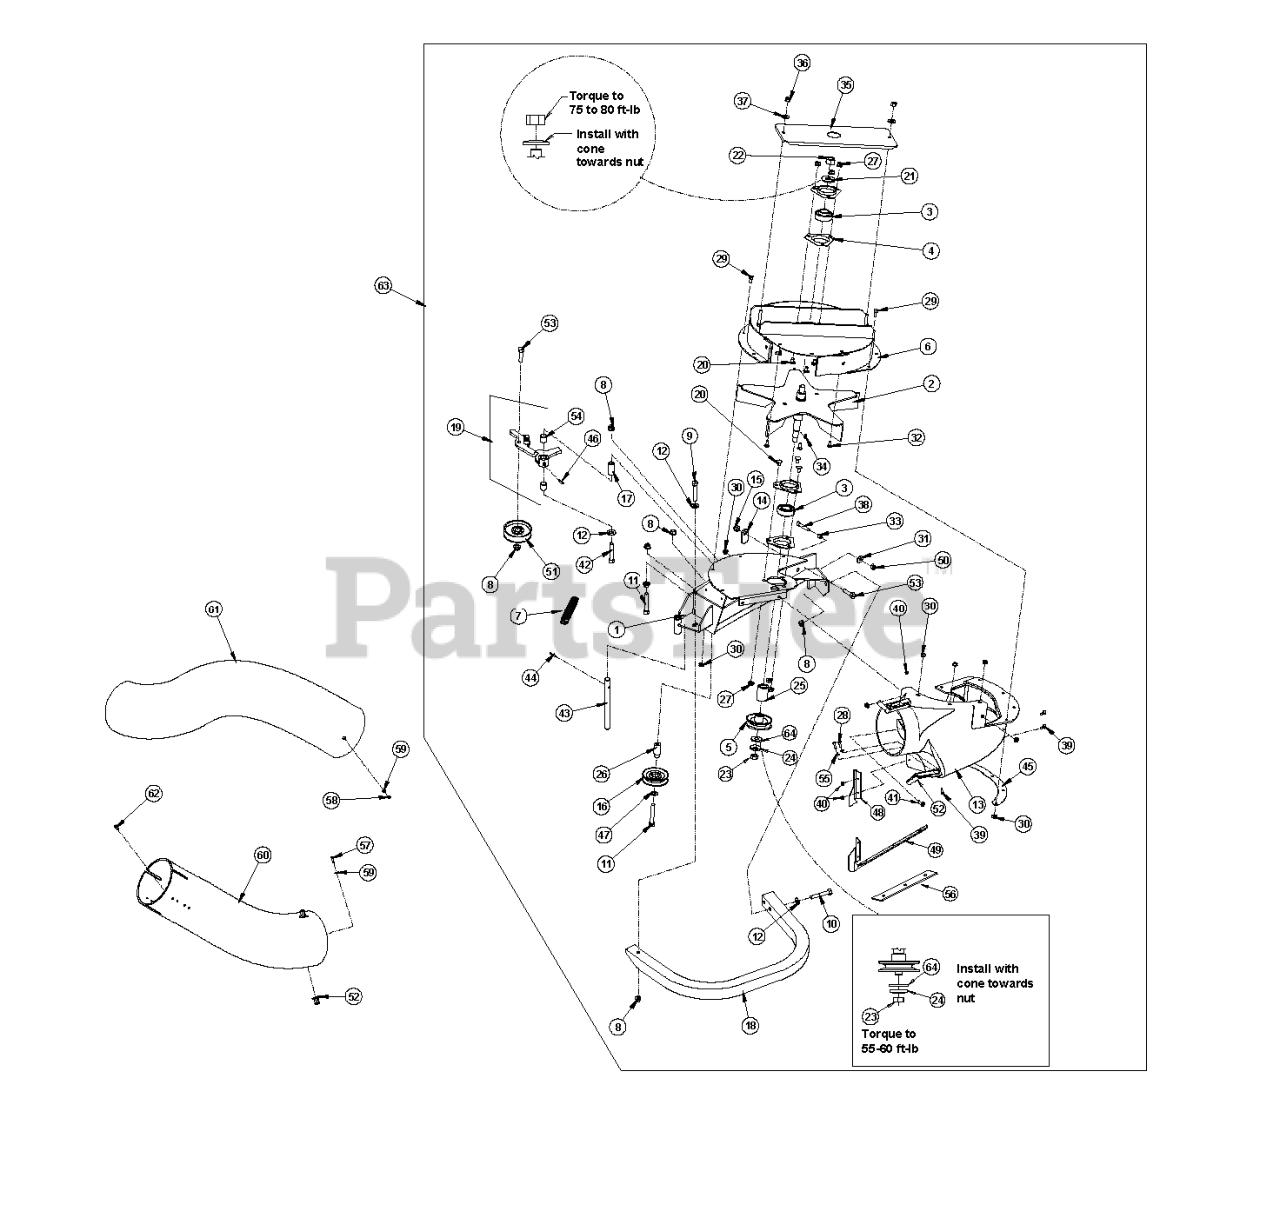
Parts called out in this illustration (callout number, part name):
1	Wld, Blower Mount
2	Wld, Impeller
3	Bearing, SPH OD
4	Housing, Flange
5	Sheave, Blower
6	Wld, Upper Housing (1-652345-03) With Decals
7	Spring, Idler
8	Nut, Whizlock 3/8-16
9	Screw, HH 3/8-16 x 1 1/4
10	Screw, HH 3/8-16 x 2 1/4
11	Screw, HH 3/8-16 x 2 1/2
12	Washer, 3/8 Std
13	Chute, Blower
14	Latch, Grass Catcher
15	Nut, Nyloc 3/8-16
16	Pulley, Idler
17	Bushing, Idler Pivot
19	Asm , Idler W/Bushings Zerk, & Decal
20	Bolt, Carriage 5/16-18 x 5/8
21	Washer, Spring Disc
22	Nut, Hex 5/8-18
23	Nut, Jam 1/2-20
24	Washer, Spring Disc
27	Nut, Whizlock 5/16-18
28	Screw, PPH #10-24 x 5/8
29	Screw, HH 1/4-20 x 5/8
30	Nut, Whizlock 1/4-20
31	Washer, Spring Disc 5/16
32	Bolt, Carriage 1/4-20 x 5/8
33	Bushing, Locator
34	Key, Woodruff #61 5/8 x 3/16
35	Cover, Bearing (103-3586-03) With Decal
36	Nut, Nyloc 5/16-18 Thin
37	Washer, 5/16 Std
38	Screw, Socket HD 5/16-18 x 1 1/4
39	Screw, CRTH #10-24 x 3/4
40	Nut, Whizlock #10-24
41	Screw, CRTH 1/4-20 x 3/4
42	Screw, Socket But HD 3/8-16 x 1 3/4
43	Pin, Grass Catcher
44	Roll pin
45	Plate, Blower Backing
46	Zerk, 1/8-28 Straight
47	Washer, 3/8 SAE
48	Plate, Filler (Below S/N 260,000)
49	Plate, Blocker
50	Nut, Hex 5/16-18
51	Pulley, Idler
52	Asm, Latch
53	Screw, HH 3/8-16 x 1 1/2
54	Bearing
55	Washer, #10 Std
56	Plate, Reinforcing (Below S/N 260,000)
57	Screw, PPH #10-24 x 5/8
58	Nut, Nyloc #10-24
59	Washer, #10 Std
60	Tube, Lower
61	Tube, Upper 52"
62	Screw, Slotted HH #10-24 x 3/4
63	Asm, Blower, (Includes Items 1-56 & Decals)
